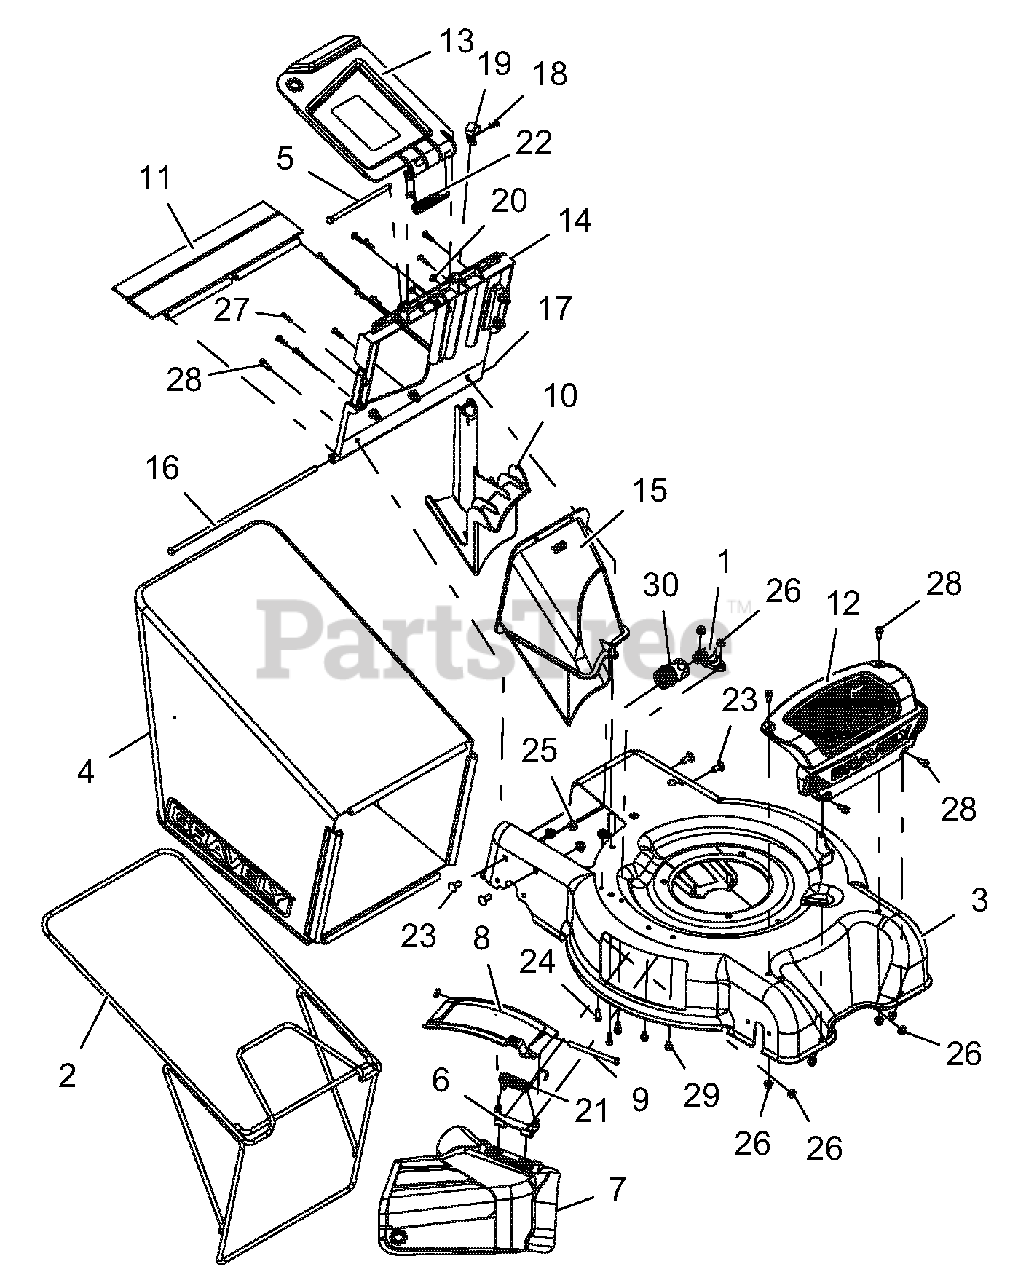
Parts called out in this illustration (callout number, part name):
1	ASM, WASHOUT PORT W/ O-RING
2	FRAME, BAGGER
3	WLDMT, DECK XD3
4	BAGGER, GRASS GRAVELY
5	PIN, 5/16 x 5.50
6	BRKT, HINGE LM
7	CHUTE, SIDE DISCHARGE - LM
8	COVER, SIDE DISCHARGE - LM
9	PIN, SIDE DISCHARGE
10	PLUG, MULCH
11	GUARD, REAR
12	TRIM, FRONT
13	DOOR, REAR
14	HANGER, BAG
15	CHUTE, REAR DISCHARGE
16	ROD, REAR GUARD
17	NUT, PUSH .312
18	PIN, HAIR INT .08 x .18 x 1.18 YWZC
19	CLAMP, LM CABLE
20	PLUG, 5/16 HOLE, .125 MATL PLASTIC
21	SPRG, TORSION
22	SPRG, TORSION
23	BLT-RDHDSQNK .31-18 x .75 G5 YWZC
24	BLT-HEX .25-20 x .63 GR5 YWZC
25	NUT, LK-TOP-FLG .312-18 YWZC
26	NUT, LK-TOP-FLG .25-20 YWZC
27	SCR-TAP #12-14 x .75 PLASTITE BLZC
28	SCR-TAP .25-20 x .62 HWH TR YWZ
29	SCR-TAP .25-20 x .37 HWH YWZ TR
30	Coupling, Quick Disconnect
